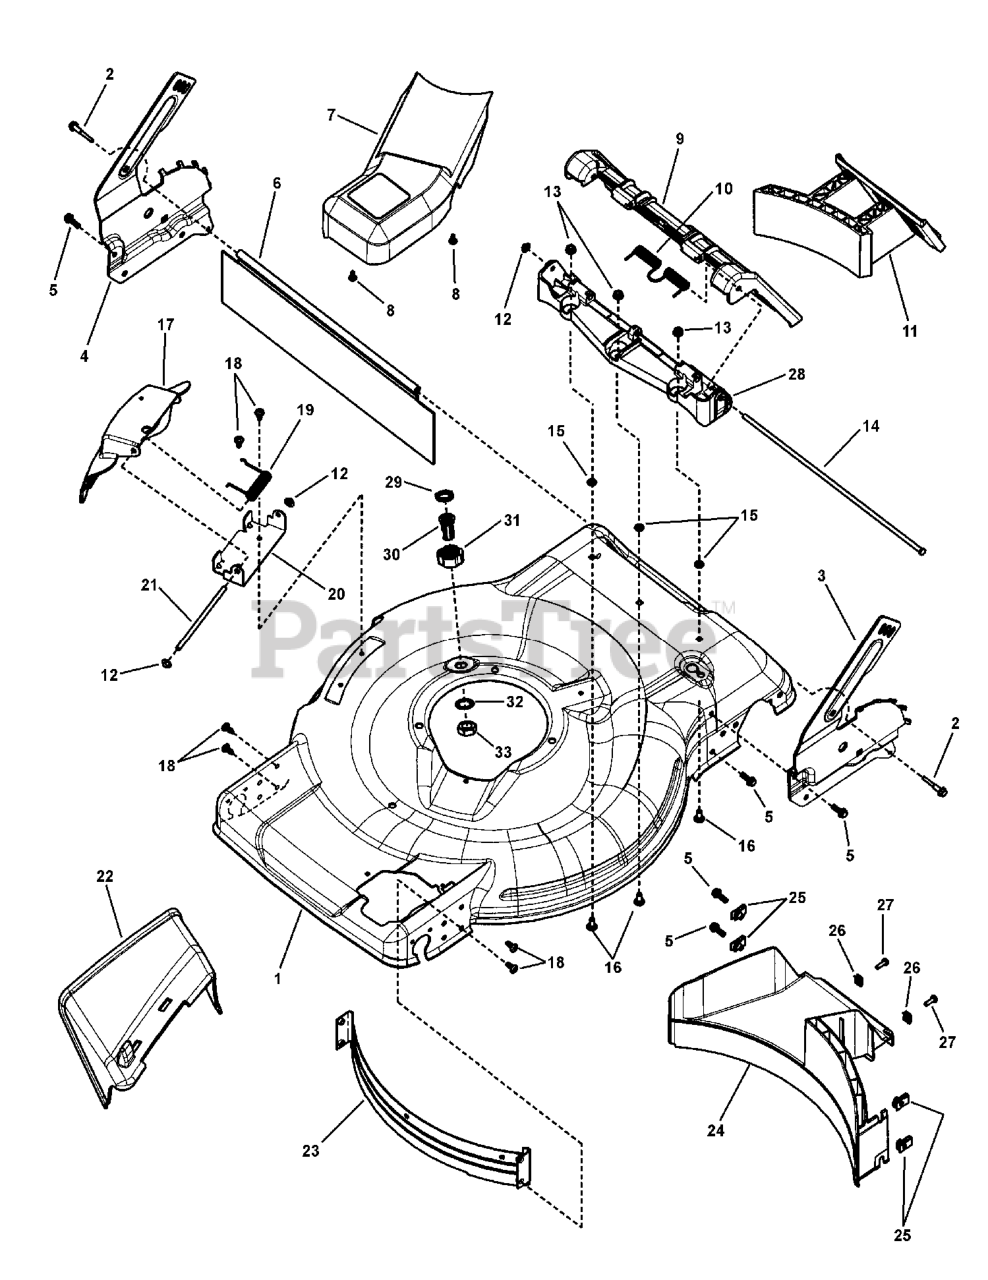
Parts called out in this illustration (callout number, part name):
1	DECK, 22", Front Wheel Drive, Washout
2	BOLT, Drag Shield, 1/4-20 x 1-1/2"
3	BRACKET, Lower Handle, LH, Hi-Wheel
4	BRACKET, Lower Handle, RH, Hi-Wheel
5	BOLT, 1/4-20 x 3/4" Hex Flange Lock, GR 5
6	GUARD, Rear 22"
7	ASSEMBLY, Belt Cover w/Heat Patch
8	SCREW, 4.8 x 1.59 x 13mm, Round Washer Head Hi-Lo (Torx)
9	DOOR, Rear Discharge
10	REAR DOOR SPRING, Torsion
11	PLUG, Mulching, 22" Deck
12	PUSHNUT, 1/4"
13	NUT, 1/4-20 Hex Flange Lock
14	ROD, Pivot, Rear Door
15	RETAINER, 1/4" Bolt
16	BOLT, 1/4-20 x 5/8" Flat Head Square Neck, GR 5
17	COVER, Mulching
18	SCREW, 1/4-20 x .550 Pan Head Torx (T-30)
19	CHUTE SPRING, Torsion
20	BRACKET, Chute
21	ROD, Pivot
22	CHUTE, Side Discharge, 22" WBM
23	BAFFLE, Front
24	REAR BAFFLE, Front Wheel Drive, WBM
25	U-NUT, 1/4-20
26	SPEED NUT, #10-24 Retainer w/Extrusion
27	SCREW, #10-24 x 5/8" Hex Washer Face Self-Tap, GR 5
28	DOOR HINGE, Rear Discharge
29	WASHER, Hose
30	ADAPTOR, Washout Port, WBM
31	COUPLING, Hose
32	WASHER, 5/8" Internal Tooth Lock
33	NUT, 5/8-11 NC-2B Hex Jam
